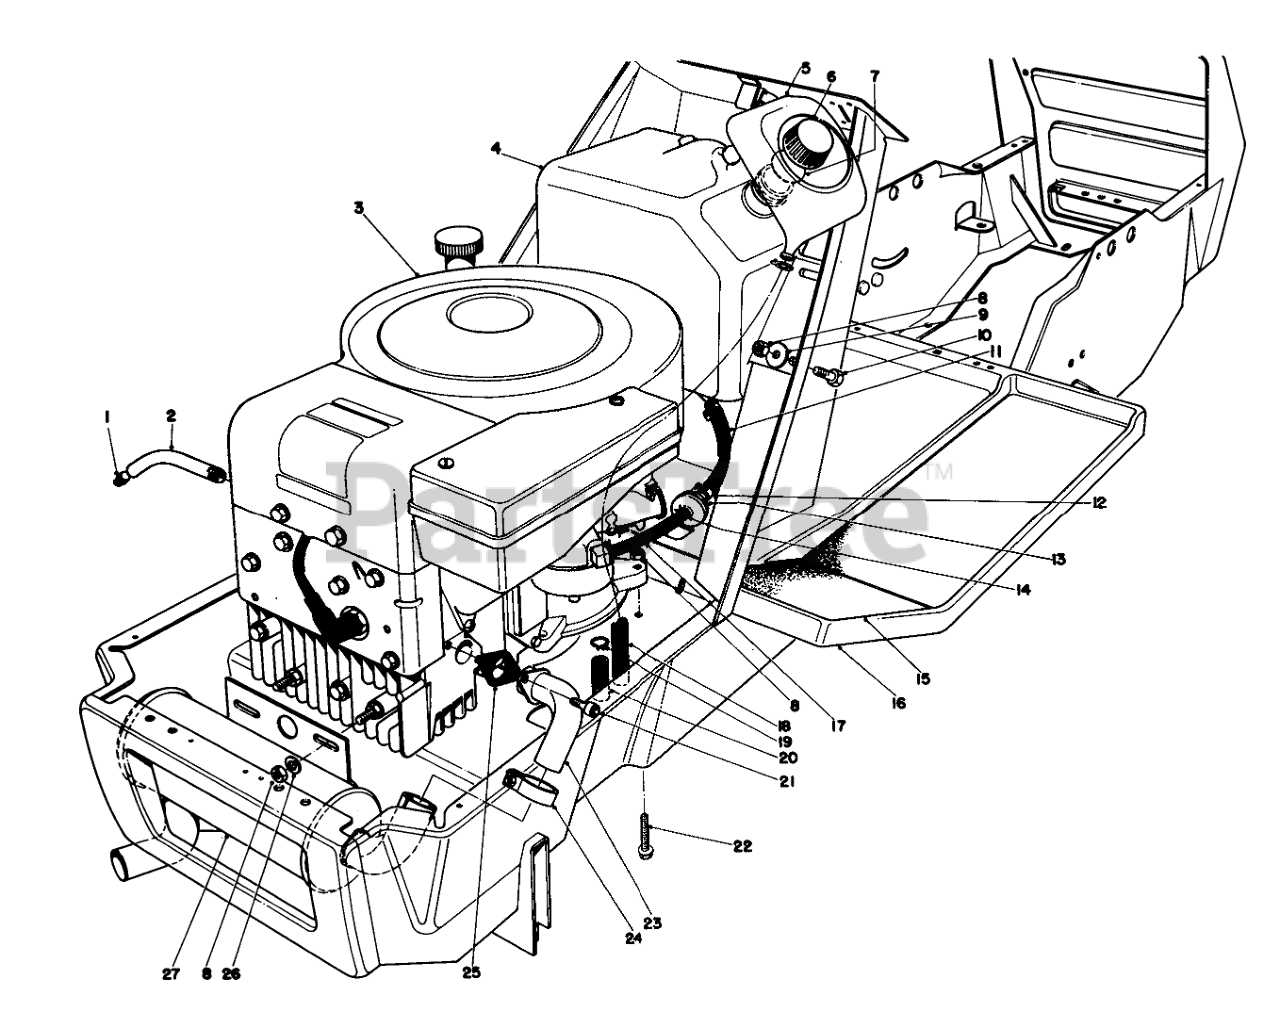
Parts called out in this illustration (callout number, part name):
1	PLUG-PIPE, SQH
2	OIL DRAIN TUBE
3	Engine
4	Gas Tank (Incl. Ref. #5)
5	Funnel-Overflow
6	Gas Cap (Incl. Ref. #7)
7	Gasket Gas Cap
8	NUT-LOCK, CONE
9	WASHER
10	SCREW-HH
11	Gas Hose
12	CLAMP-HOSE
13	Nut
14	Clamp
15	LH FOOT TREAD
16	Frame
17	GAS HOSE
18	FUNNEL HOSE
19	HOSE CLAMP
20	Hose-Carburetor Drain
21	SCREW-HSH
22	SCREW-HH
23	Exhaust Pipe
24	MUFFLER CLAMP
25	Exhaust Gasket
26	WASHER-PLAIN
27	MUFFLER
